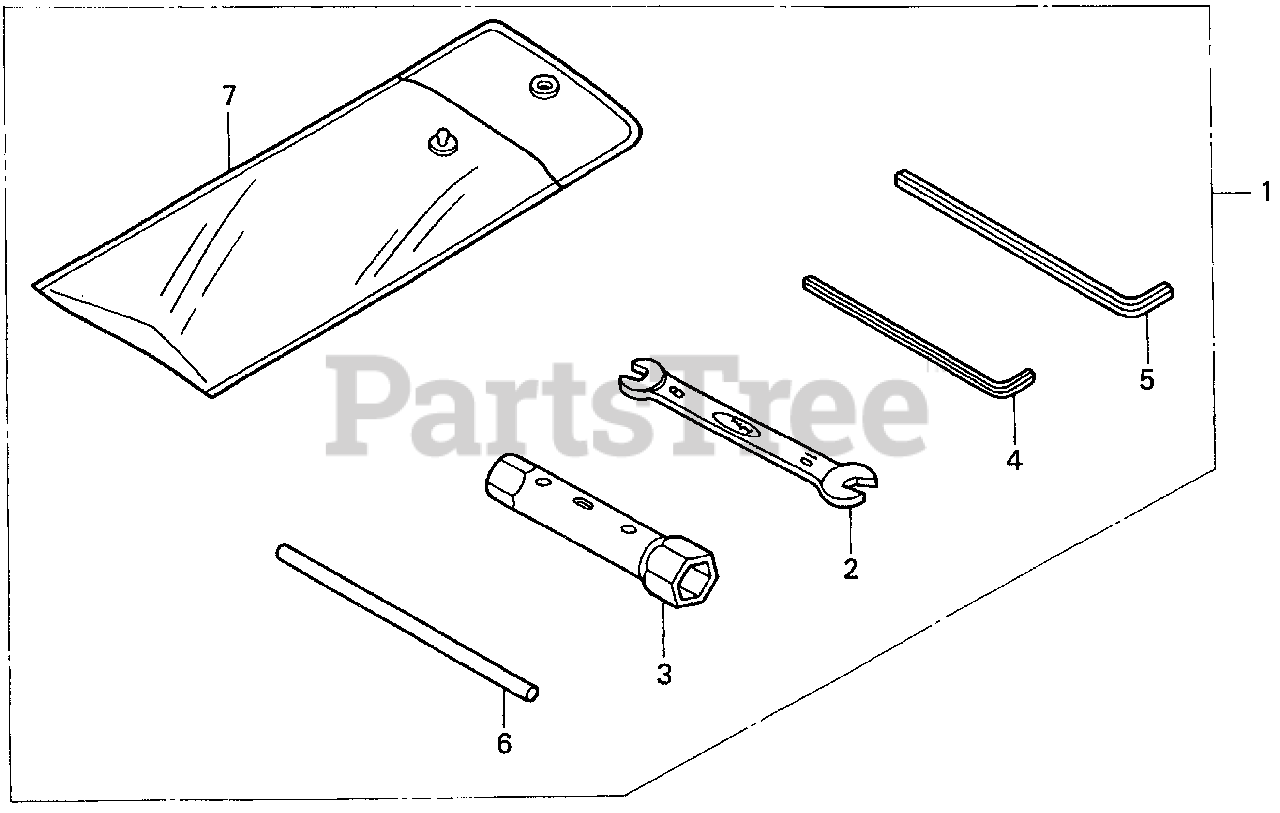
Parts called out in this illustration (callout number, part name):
2	SPANNER (8X10)
3	WRENCH, SPARK PLUG
4	WRENCH, HEX. (4MM)
5	WRENCH, HEX. (5MM)
6	BAR A, HANDLE
7	BAG, TOOL (160MM)
